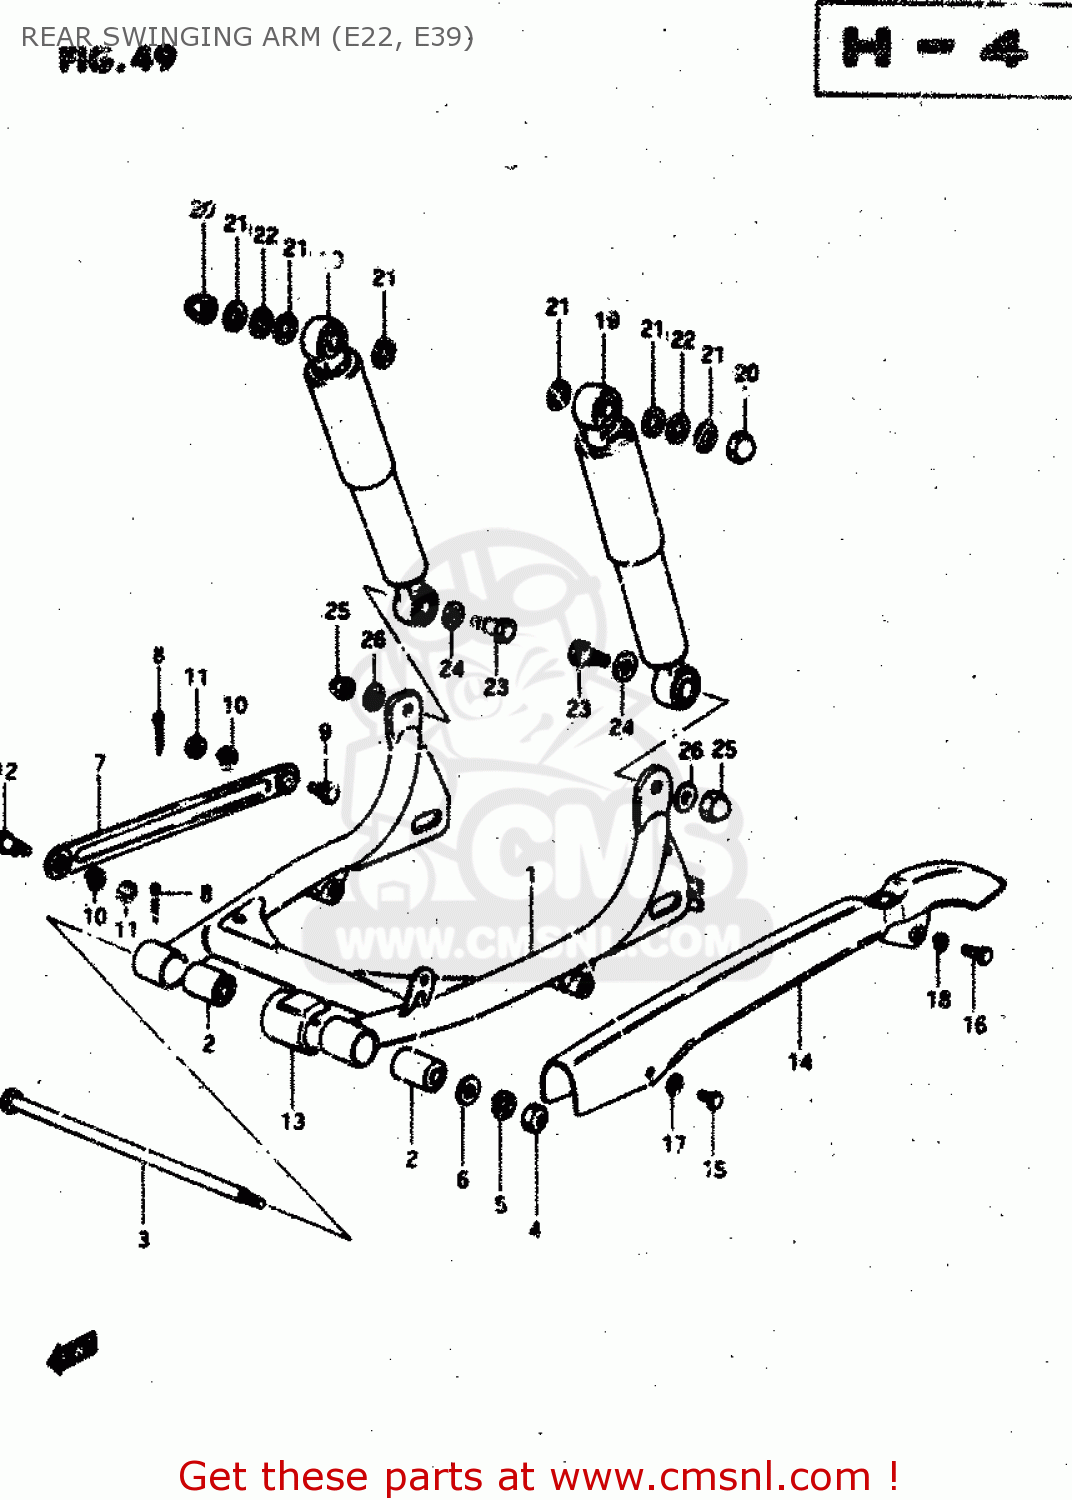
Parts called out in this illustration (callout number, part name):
1	SWINGING ARM SET, REAR
2	BUSHING(10X23X35)
3	SHAFT,REAR SWING ARM
4	NUT
5	LOCK WASHER
6	WASHER
7	LINK,RR BRAKE TORQUE
8	PIN
9	BOLT(8X26.5)
10	LOCK WASHER
11	NUT
12	BOLT(8X22.5)
13	BUFFER,CHAIN TOUCH DEFENSE
14	CHAIN CASE
15	BOLT(6X6)
16	BOLT
17	WASHER
18	LOCK WASHER
19	SHOCK ABSORBER ASSY
20	NUT, LOWER LH
21	WASHER
22	WASHER(10.5X24X3.2)
23	BOLT
24	WASHER
25	NUT, LOWER LH
26	WASHER
